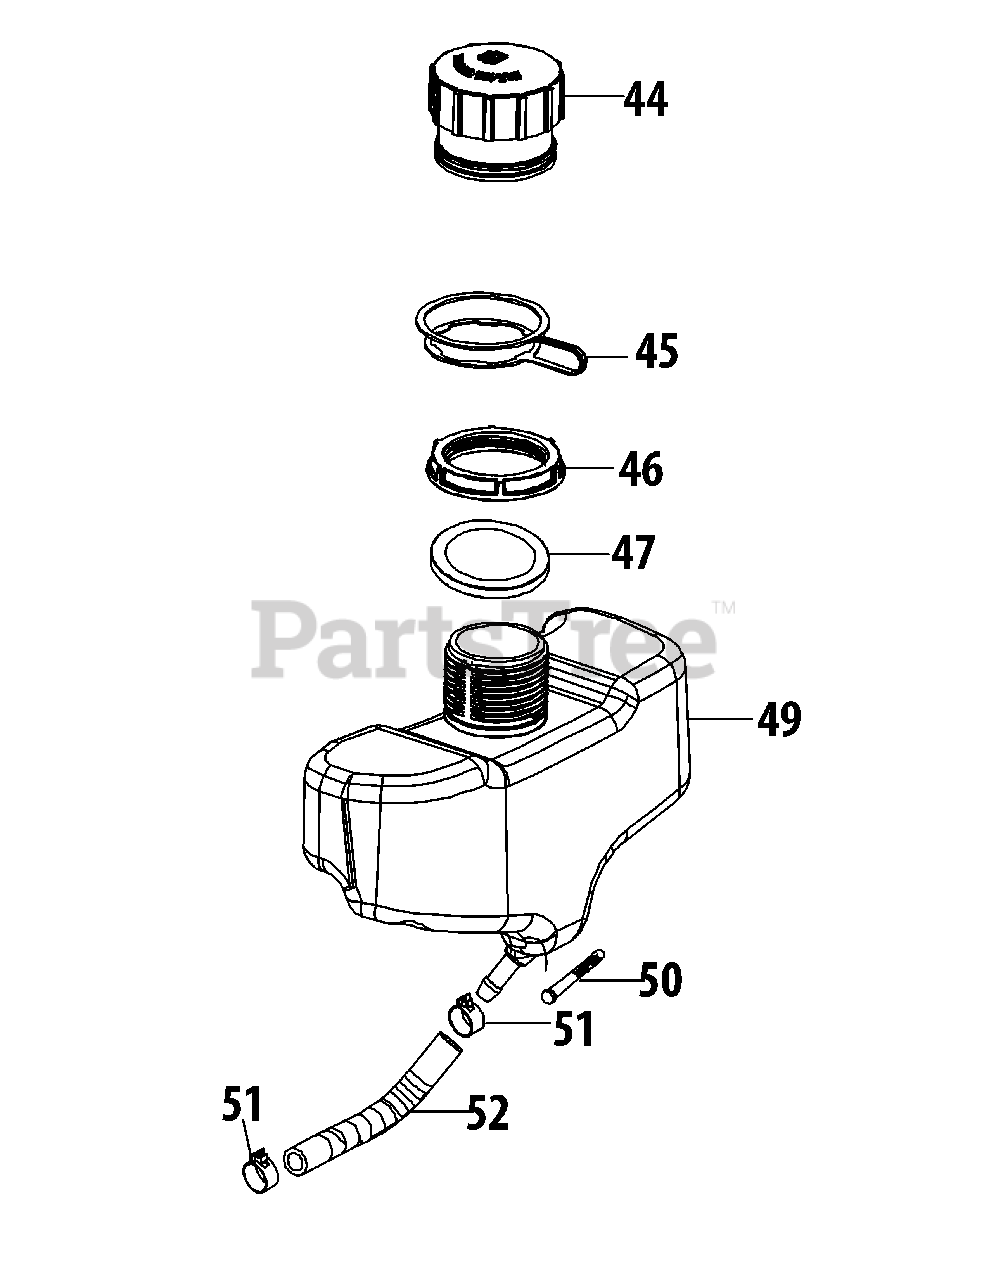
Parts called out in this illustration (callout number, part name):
44	Fuel Cap Assembly
45	Fuel Cap Tether
46	Fuel Tank Nut
47	Fuel Tank Upper Grommet
49	Fuel Tank
50	Fuel Filter
51	Fuel Hose Clamp
52	Fuel Hose
